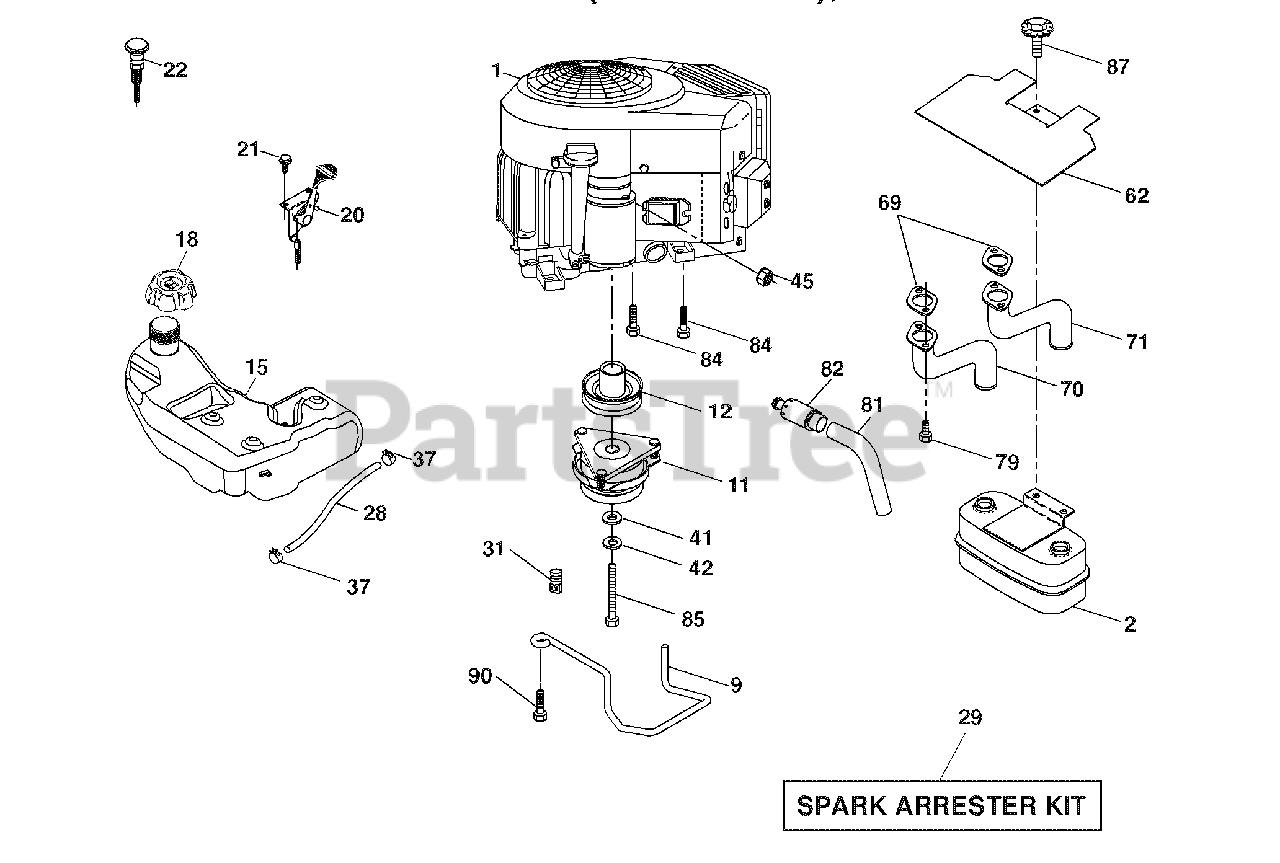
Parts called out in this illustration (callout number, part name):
9	Keeper Belt Engine
11	Clutch Electric
12	Pulley Engine
15	Tank Fuel
18	Cap Asm
20	Control Throttle
21	Screw #10 x 0.750 BOS Thread
22	Control Choke
28	Fuel Line
29	Spark Arrester Kit
31	Clip Push-In
37	Clamp Hose
41	Washer 1-1/2 OD x 15/32 ID x .250
42	Washer Lock 7/16
45	Nut Keps Hex 1/4-20 unc
62	Shield Heat Muffler
70	Tube Exhaust LH
71	Tube Exhaust RH
79	Screw Socket Head 5/16-18 x 1
81	Tube Drain Oil Easy
82	Plug Drain Oil
84	Screw 3/8-16 x 1-1/4
85	Bolt Hex 7/16-20 x 4 Gr. 5
87	Bolt 5/16-18 unc x 1 w/Sems
90	Screw 3/8-16 x 1
